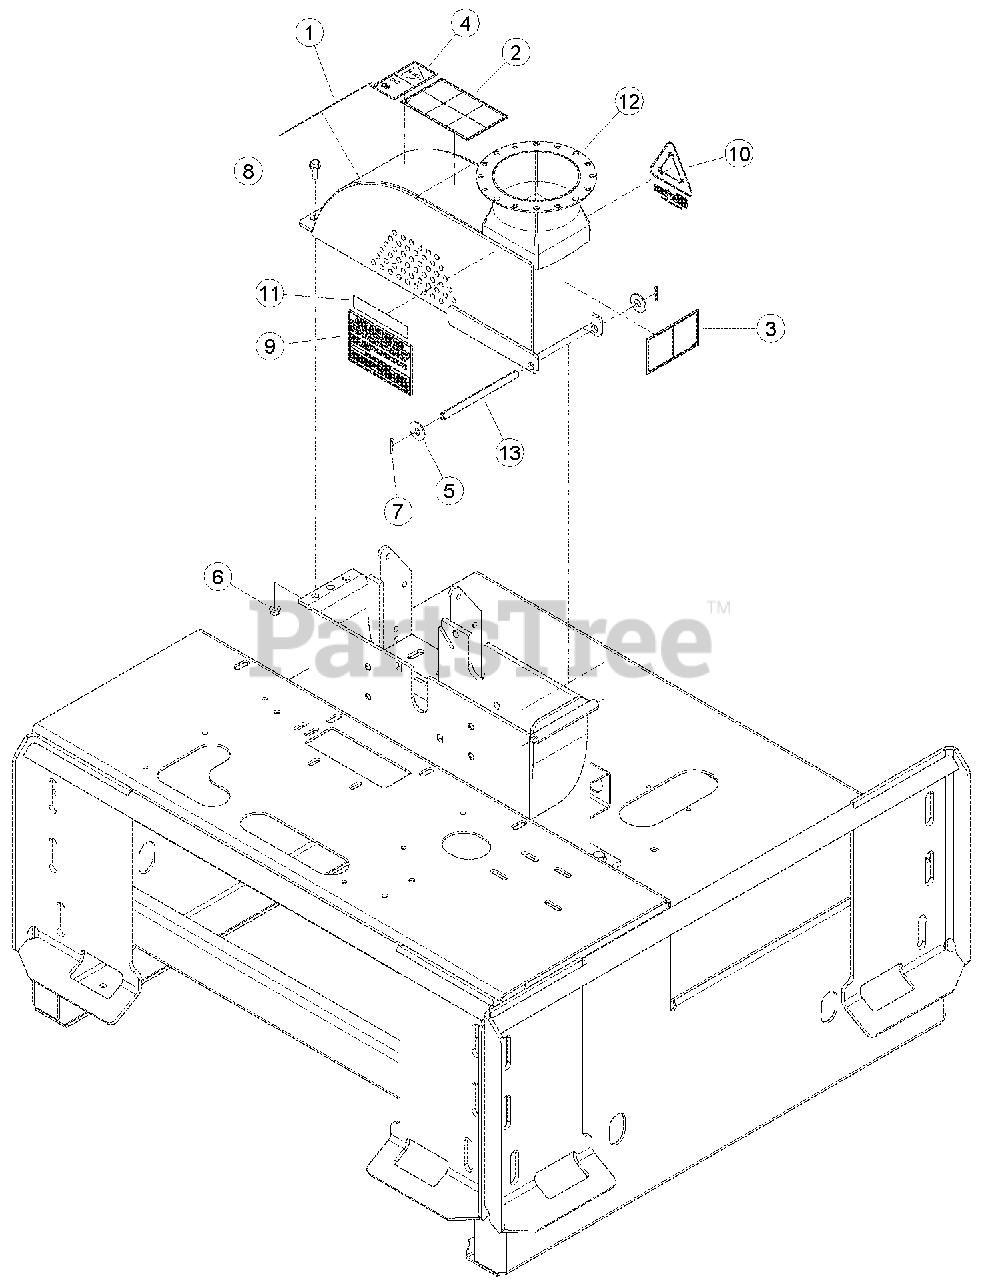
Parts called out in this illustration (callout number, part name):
1	DECAL, KNIFE ACCESS ISO
2	DECAL, OPERATING INSTRUCTIONS ISO
3	DECAL, DISCHARGE ISO
4	DECAL, MAINTENANCE ISO
5	WASHER, 1/2 FLAT ZP
6	NUT, 3/8 SERR FLANGE NC ZP
7	PIN, 1/8 X 1.00 COTTER ZP
8	BOLT, 3/8 X 1 SERR FLANGE GR5 NC ZP
9	DECAL, FLOW RATE HYDRAULIC
10	DECAL, CHIP IT
11	DECAL, MODEL CH500H
12	WELDMENT, TOP CHIPPER HOUSING
13	SHAFT, CHIPPER TOP PIVOT
